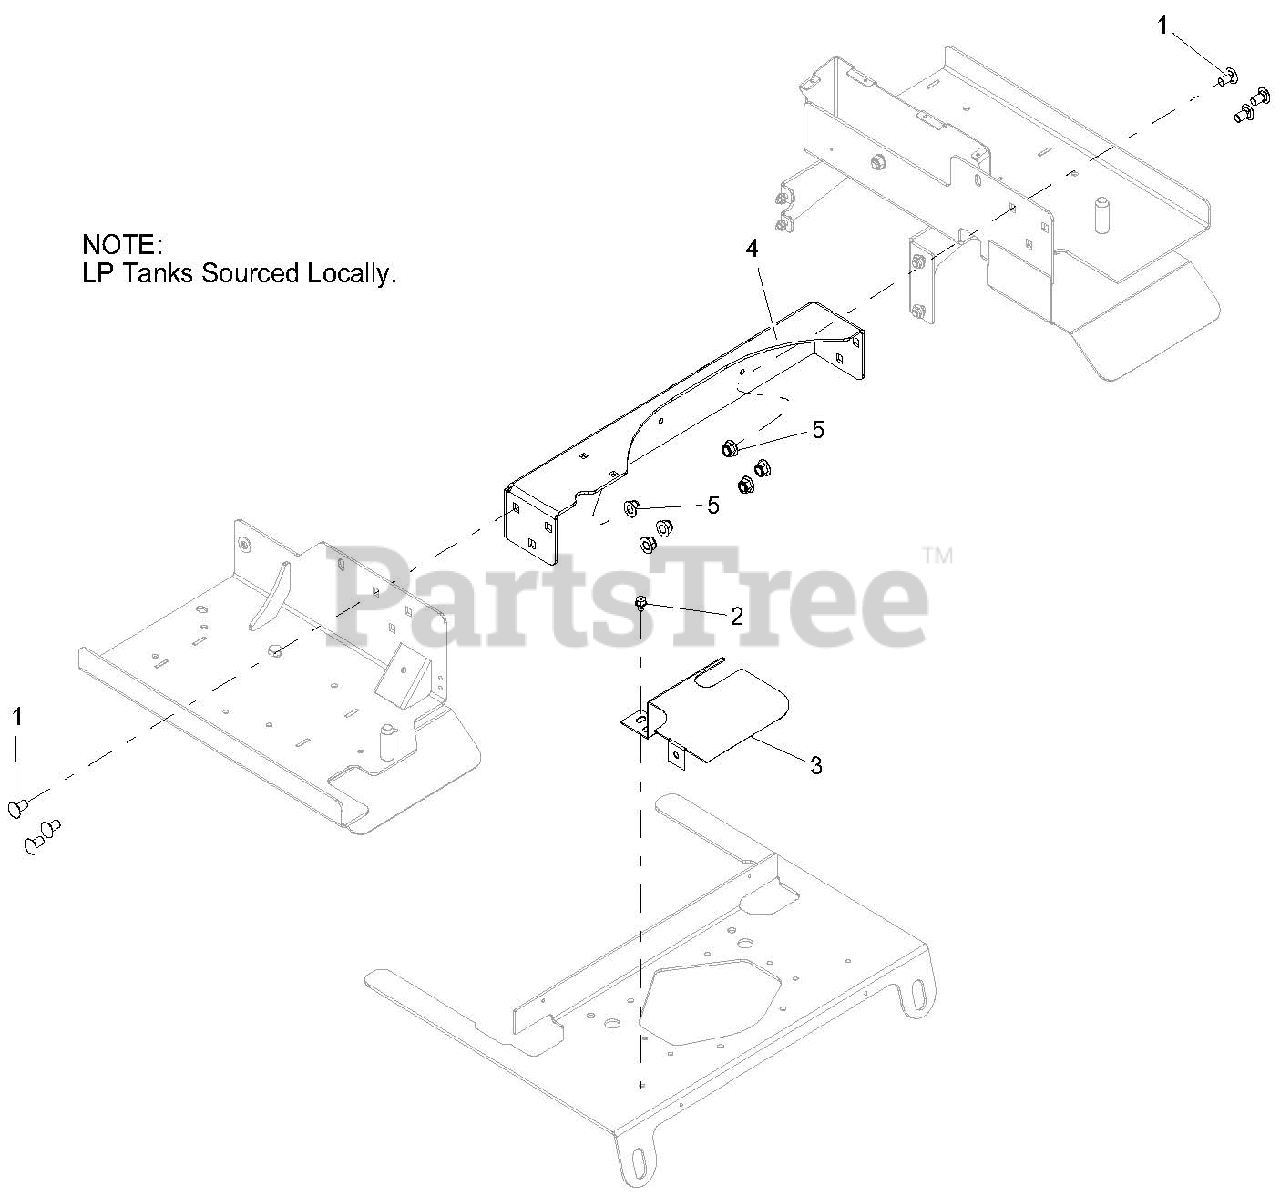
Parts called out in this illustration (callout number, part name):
1	BLT-RDHDSQNK .50-13X1.00 G5 Y
2	SCR-TAP .38-16X.50 HWH TR YWZ
3	GUARD, LP-MUFFLER-BLACK
4	TANK MNT CROSS SUPPORT W/SAFETY DECAL
5	NUT-LK-NYL-FLG .50-13 YWZC
